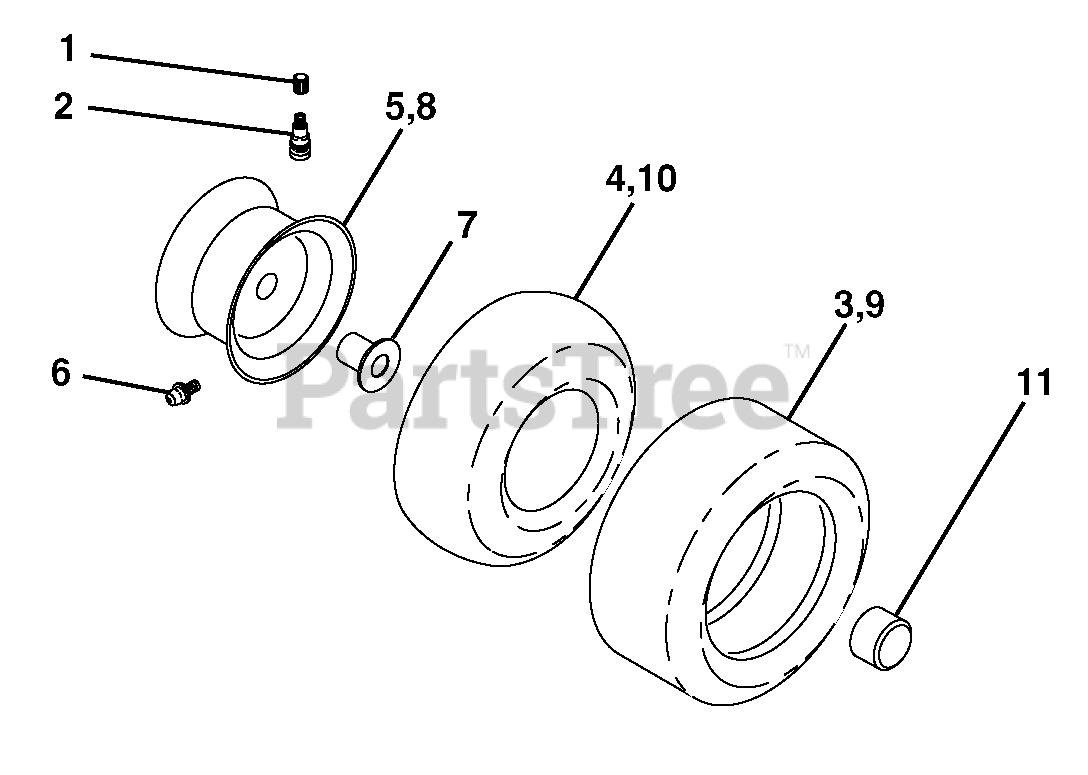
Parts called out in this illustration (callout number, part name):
1	Cap Valve Tire
2	Stem Valve
3	Tire F T 15 x 6 0 - 6
4	Tube Front
5	Rim Asm. 6" Front
6	Fitting Grease
7	Bearing Flange
8	Rim Asm. 8" Rear
9	Tire R T 18 x 9.5-8 Turf Saver
9	Tire R T 18 x 9.5-8 Turf Saver LT
10	Tube Rear
11	Cap Axle
11	Sealant, Tire (10 oz. Tube)
